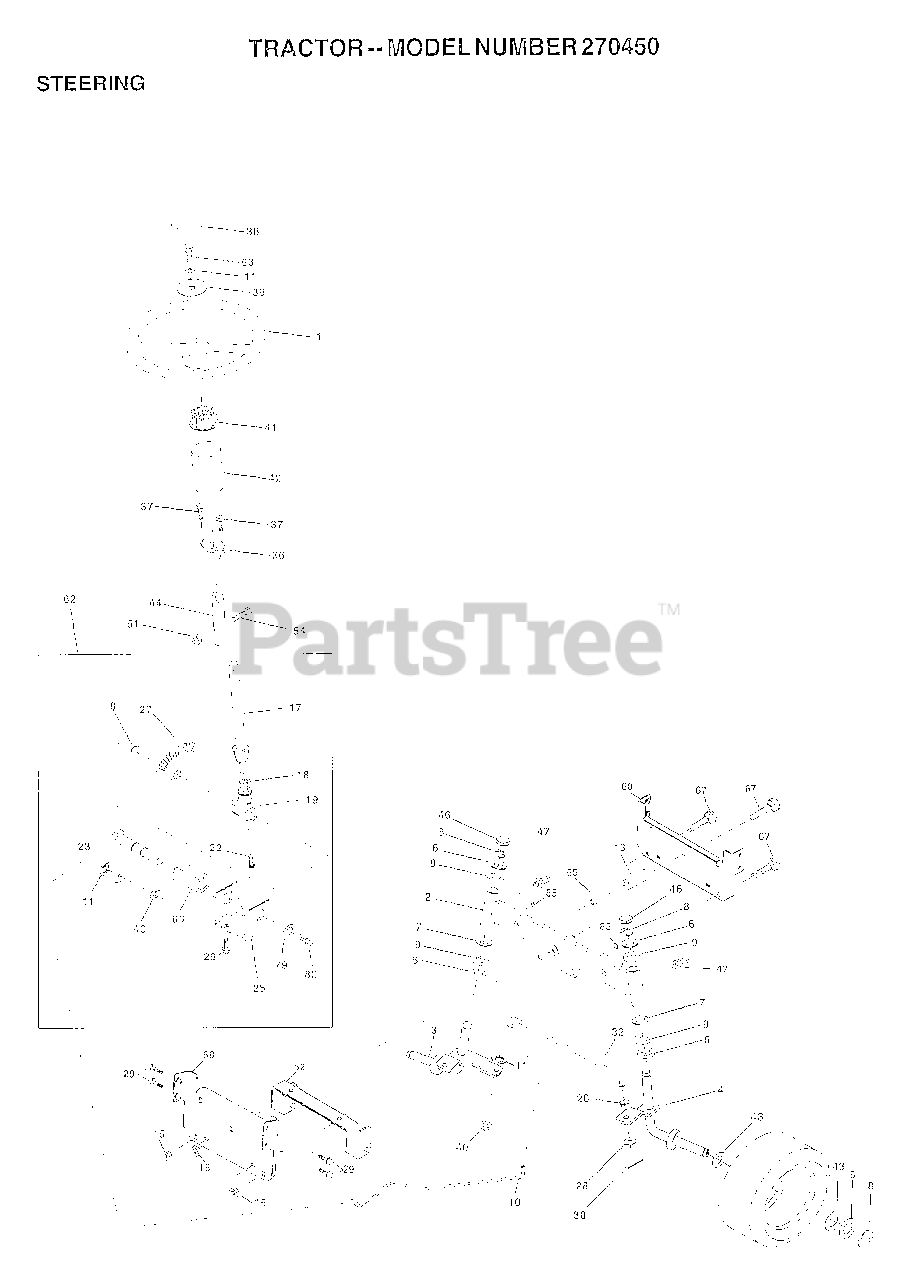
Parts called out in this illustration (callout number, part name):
1	WHEEL STR AYP BLK
2	AXLE ASM
3	SPINDLE.ASM.LH
4	"SPINDLE ASM,RH"
5	WASHER .T
6	WASHER
7	WASHER
8	RING
9	COL. SRTG. BEAR.
10	LINK DRAG
11	LOCKWASHER
13	SPACER BEARING
15	NUT.HXFLG.LOCK.
17	SHAFT ASM STEERIN
18	THRUST WASHER
19	SUPPORT.SHAFT.STEER
22	SCREW.HX.WSH.HD
23	SHAFT.ASM.PITMAN
25	BRKT-STEERING
26	BUSHING.DRAGLINK
27	GEAR SECTOR
28	WASHER
29	SCREW
30	COTTER PIN
32	TIE ROD
36	BUSHING.STEERING
37	"SCREW-TT,10-32 FL"
38	CAP STEER AYP
39	WASHER
40	GRIPCO NUT
41	ADAPTER LT
42	BOOT.STEERING.DASH.P/L
43	WASHER
44	EXT SHAFT STEERIN
46	CAP
47	ZERK M
54	BOLT
62	KIT.STEER.ASM
63	BOLT
65	"SPACER BRCAE,AXLE"
66	"BEARING-ARM,PITMA"
67	BOLT RDHD 3/8-16
68	BRACE AXLE
79	WASHER
80	BOLT.HX.NYLON3/8-16X3/
82	BRKT SUSP CHASSIS FRT
85	XMAS TREE FASTNER
